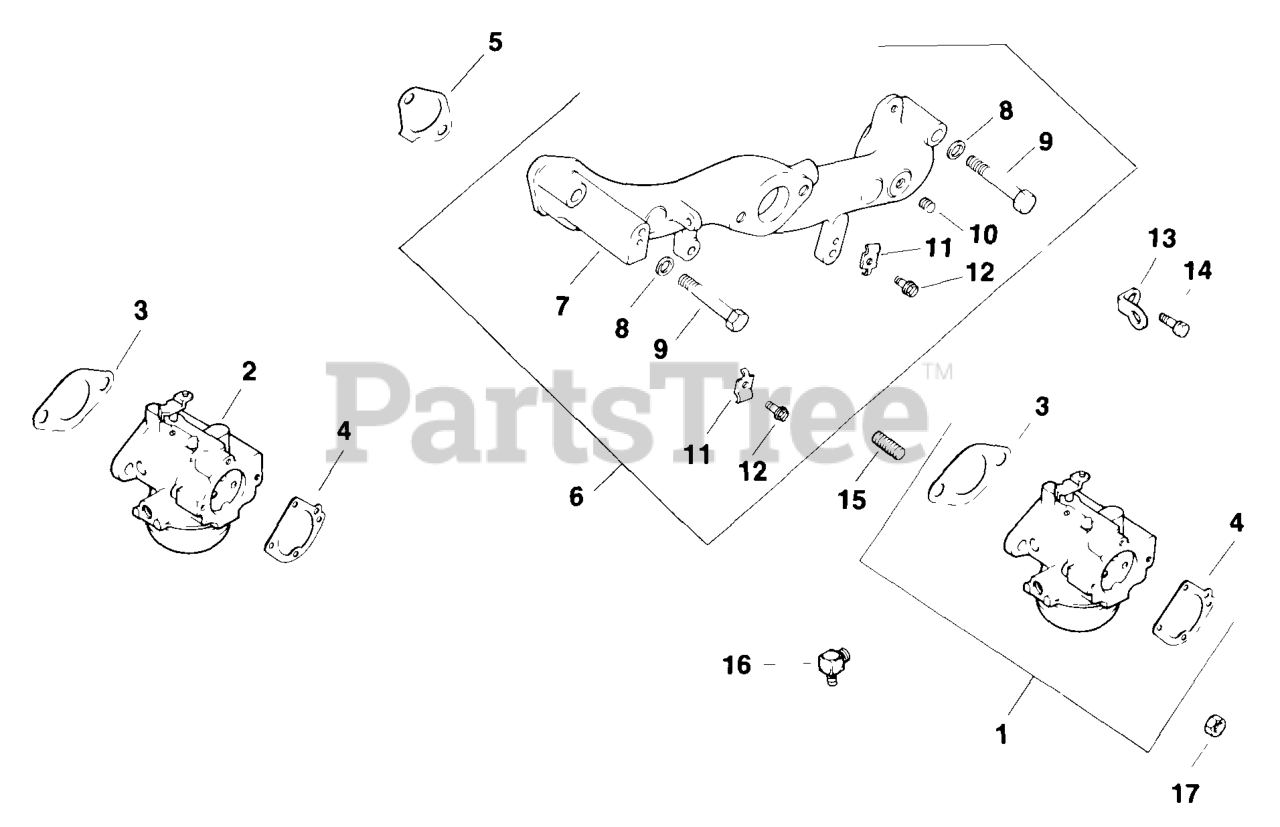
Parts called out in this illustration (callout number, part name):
1	CARBURETOR - USE 52 853 25
1	KIT, CARBURETOR
3	GASKET, CARBURETOR
4	GASKET - USE 25 041 06
6	KIT, MANIFOLD
9	SCREW,CAP HD 5/16-18x2"
10	PLUG, CTSK PIPE 1/8" USE 25 139 60-S
12	SCREW, WSH HD TAP #10-24X13/32" USE 25 086 109-S
13	STRAP - USE 28 445 01
14	SCREW, WSH HD TAP 1/4-20X3/4" USE 25 086 100-S
15	STUD, 5/16-18X1" USE 25 072 06-S
16	CONNECTOR, 90 DEG. HOSE
17	NUT, 5/16-18 GRADE 2 USE 25 100 21-S
